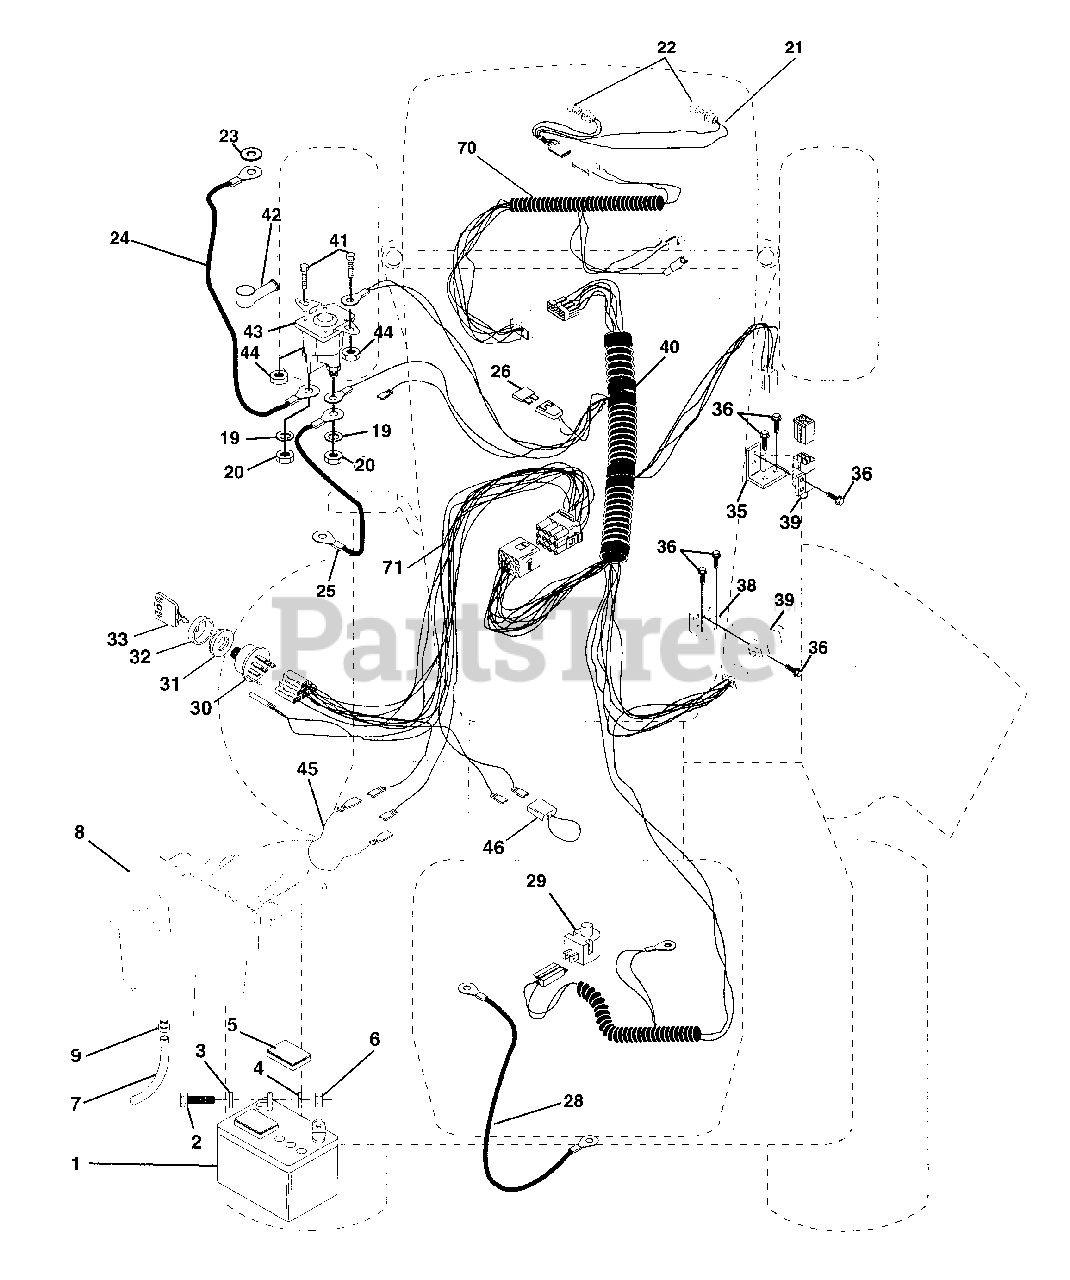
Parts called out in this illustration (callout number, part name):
1	Battery 12 Volt 25 Amp
2	Bolt Hex Hd 1/4-20unc X 3/4
3	Washer 9/32 X 5/8 X 16 Ga
4	Washer Lock Hvy Helical 1/4
5	Caps Battery 20/25/30 AMP
6	Nut Fin Hex 1/4-20 Unc
7	Tube Plastic 20"
8	Battery Case Hng Mech
9	Clamp Hose Olive
19	Washer Lock 1/4
20	Nut Jam Hex 1/4-20 Unc
21	Harness Asm Light W/4152j
22	Bulb Light #1156
23	Washer Lock Internal Tooth 1/4
24	Cable Battery 6 Ga 11" red
25	Cable Battery 6 Ga 43" red
26	Fuse 30 AMP Auto Green
28	Cable Ground 6 Ga 12" black
29	Switch Plunger Nc Gray
30	Switch Ign 4 Pos.
31	Nut Ignition
32	Cover Sw Key Blk 1 25 Text SLT
35	Bracket Switch Interlock
36	Screw Tap Hex #10-24unc X 1/2
38	Bracket Switch Clutch
39	Switch Intlk Clutch Gry 4 Term
40	Harness Ign Lt Mech Dash
41	Bolt Fin Hex 1/4-20 x 1/2
42	Cover Terminal Red
43	Solenoid
44	Nut Keps Hex 1/4-20 Unc
45	Adapter Ammeter rectangular
46	Protection Wire Loop (Hourmeter)
70	Harness Eng. B&S
71	Harness Dash Lt Private Label
